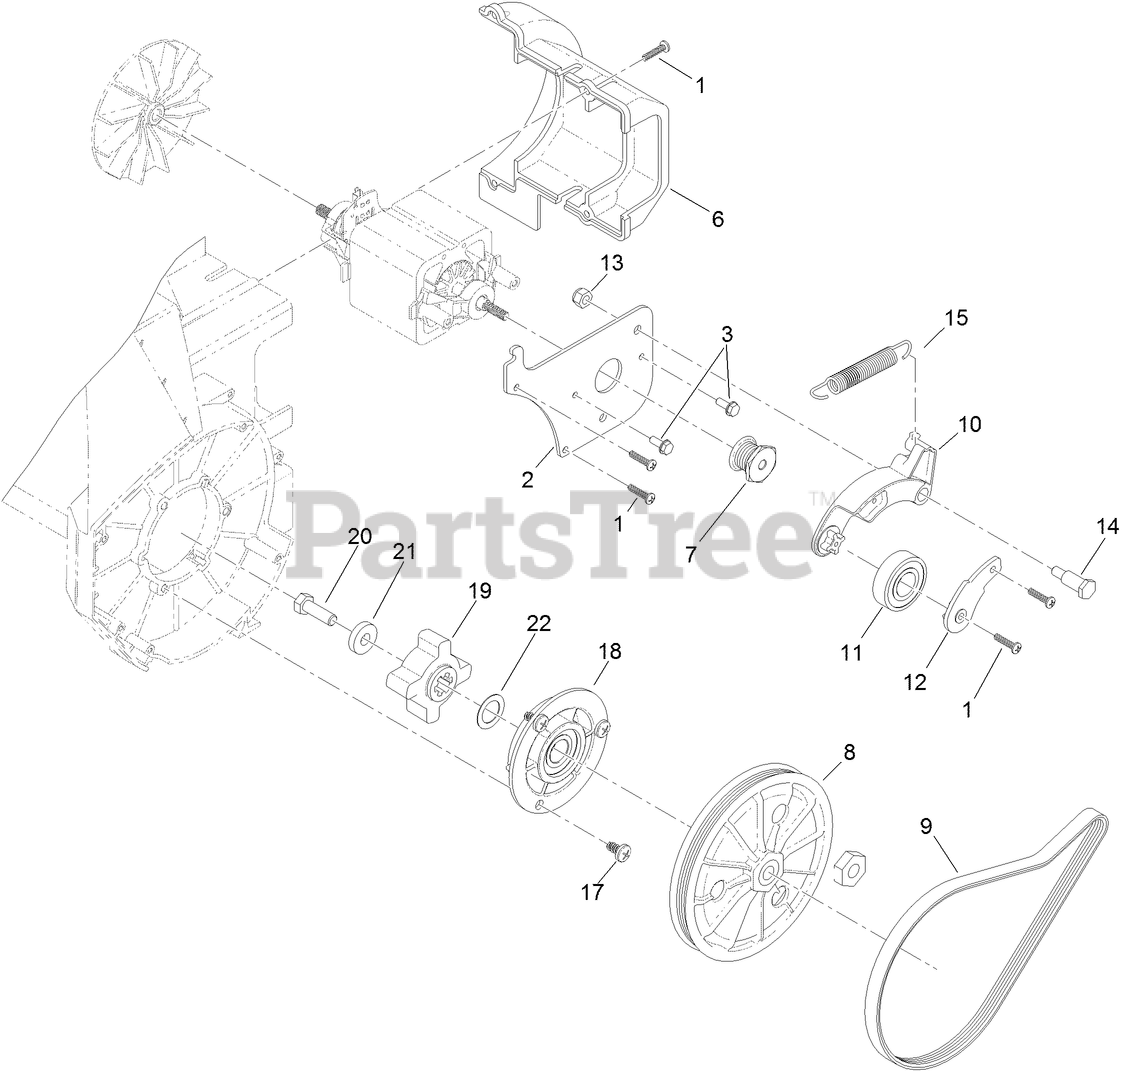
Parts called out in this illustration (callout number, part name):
1	SCREW-PPH
2	PLATE-MOTOR
3	SCREW-HWH
6	COVER-MOTOR
7	PULLEY-DRIVE
8	PULLEY ASM
9	BELT-DRIVE
10	ARM-IDLER
12	RETAINER-IDLER
13	NUT-LOCK, NI
14	BOLT-SHOULDER
15	SPRING-IDLER
17	SCREW-SEAT, SWITCH
18	PILLOW BLOCK ASM
19	COUPLER-PULLEY
22	WASHER-PLAIN
